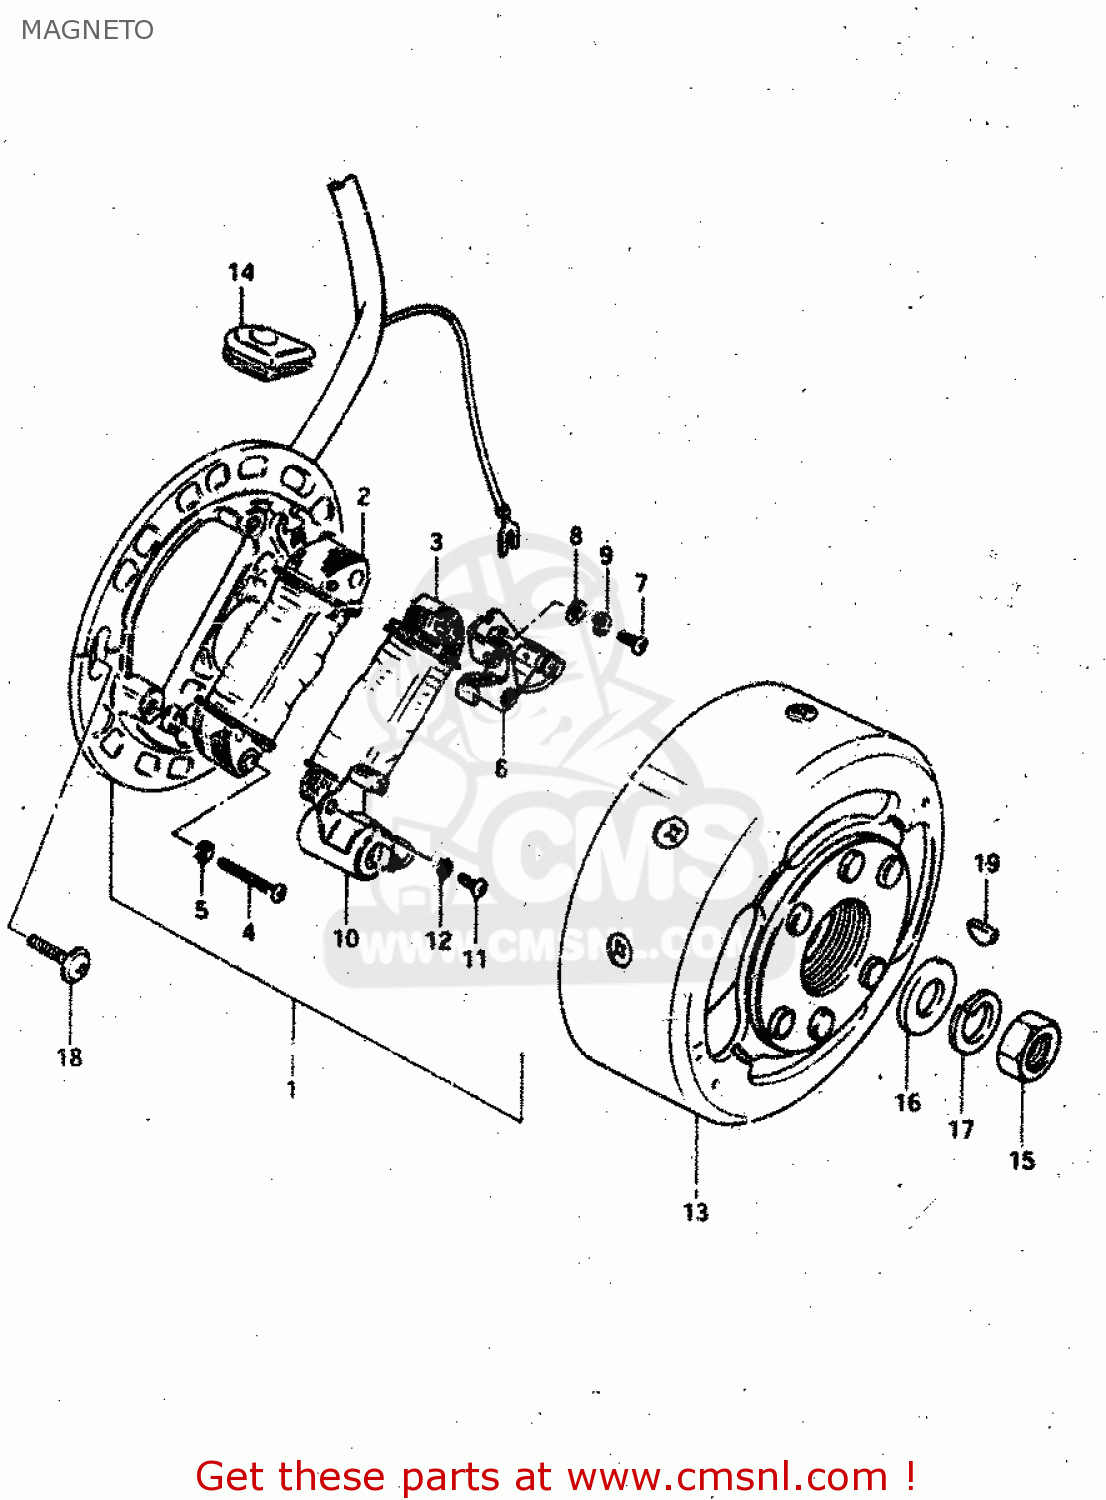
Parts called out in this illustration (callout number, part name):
1	STATOR ASSY
2	COIL, LIGHTING
3	COIL,PRIMARY
4	SCREW (4X30)
5	LOCK WASHER
6	POINT ASSY,CONTACT
7	SCREW(4X10)
8	WASHER
9	LOCK WASHER
10	CONDENSER
11	SCREW
12	LOCK WASHER
13	ROTOR ASSY
14	GROMMET
15	NUT (10MM)
16	WASHER
17	LOCK WASHER
18	SCREW(5X14)
19	KEY
